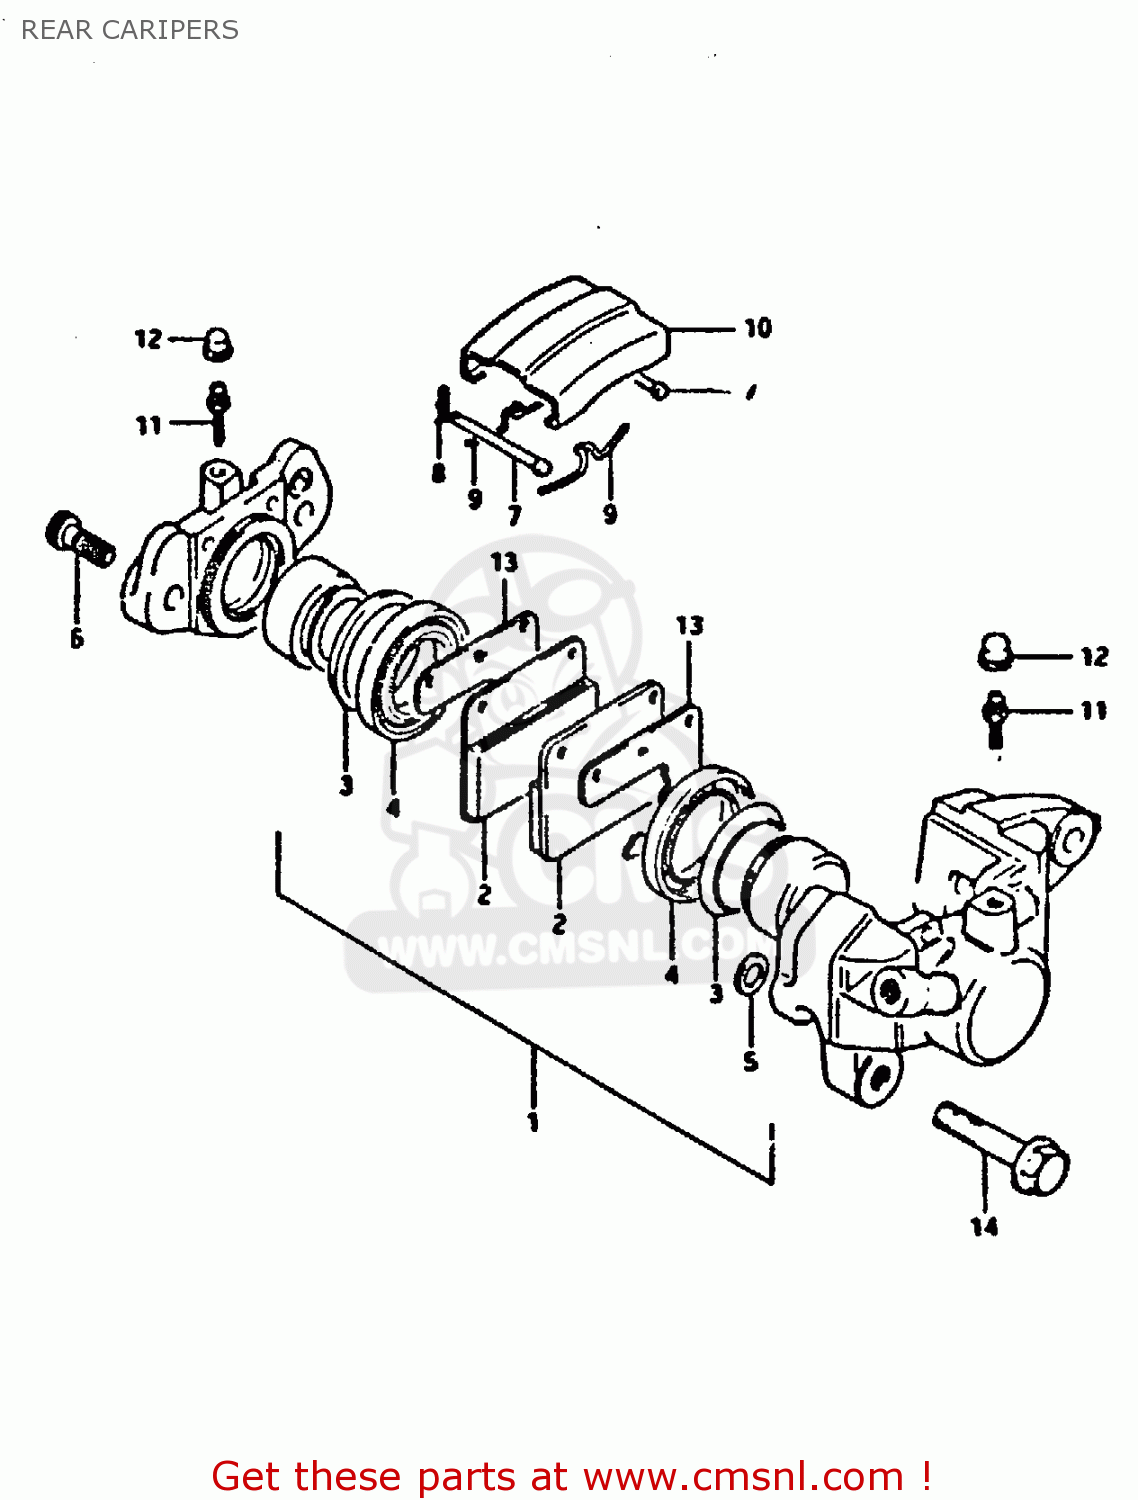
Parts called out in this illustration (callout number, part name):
1	PISTON SET
2	PAD,BRAKE (MCA)
3	SEAL,PISTON
4	BOOT,PISTON
5	SEAL,PISTON
6	BOLT,HOUSING
7	PIN,PAD
8	CLIP,PAD PIN
9	SPRING
10	COVER,DUST
11	BLEEDER
12	CAP,BREATHER
13	SHIM,RR CALIPER
14	BOLT
